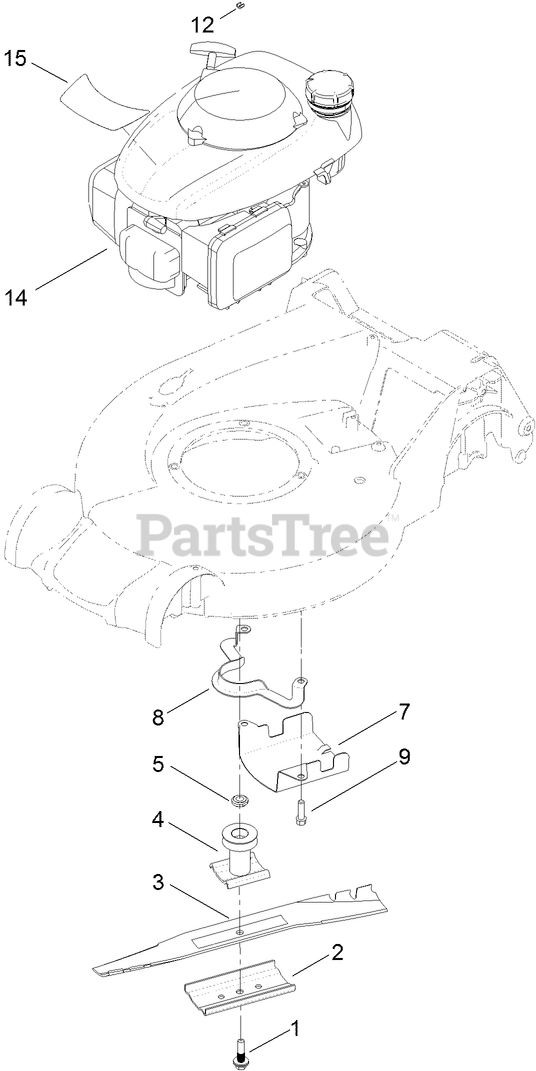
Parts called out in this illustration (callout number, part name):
1	BOLT-BLADE
2	SUPPORT-BLADE
4	DRIVER-BLADE
5	SPACER-DRIVER
7	SHIELD-GRASS
8	GUIDE-BELT
12	STOP-ROPE
14	ENGINE-HONDA,GCV160A0-S3TEGAS
15	DECAL-ENGINE
